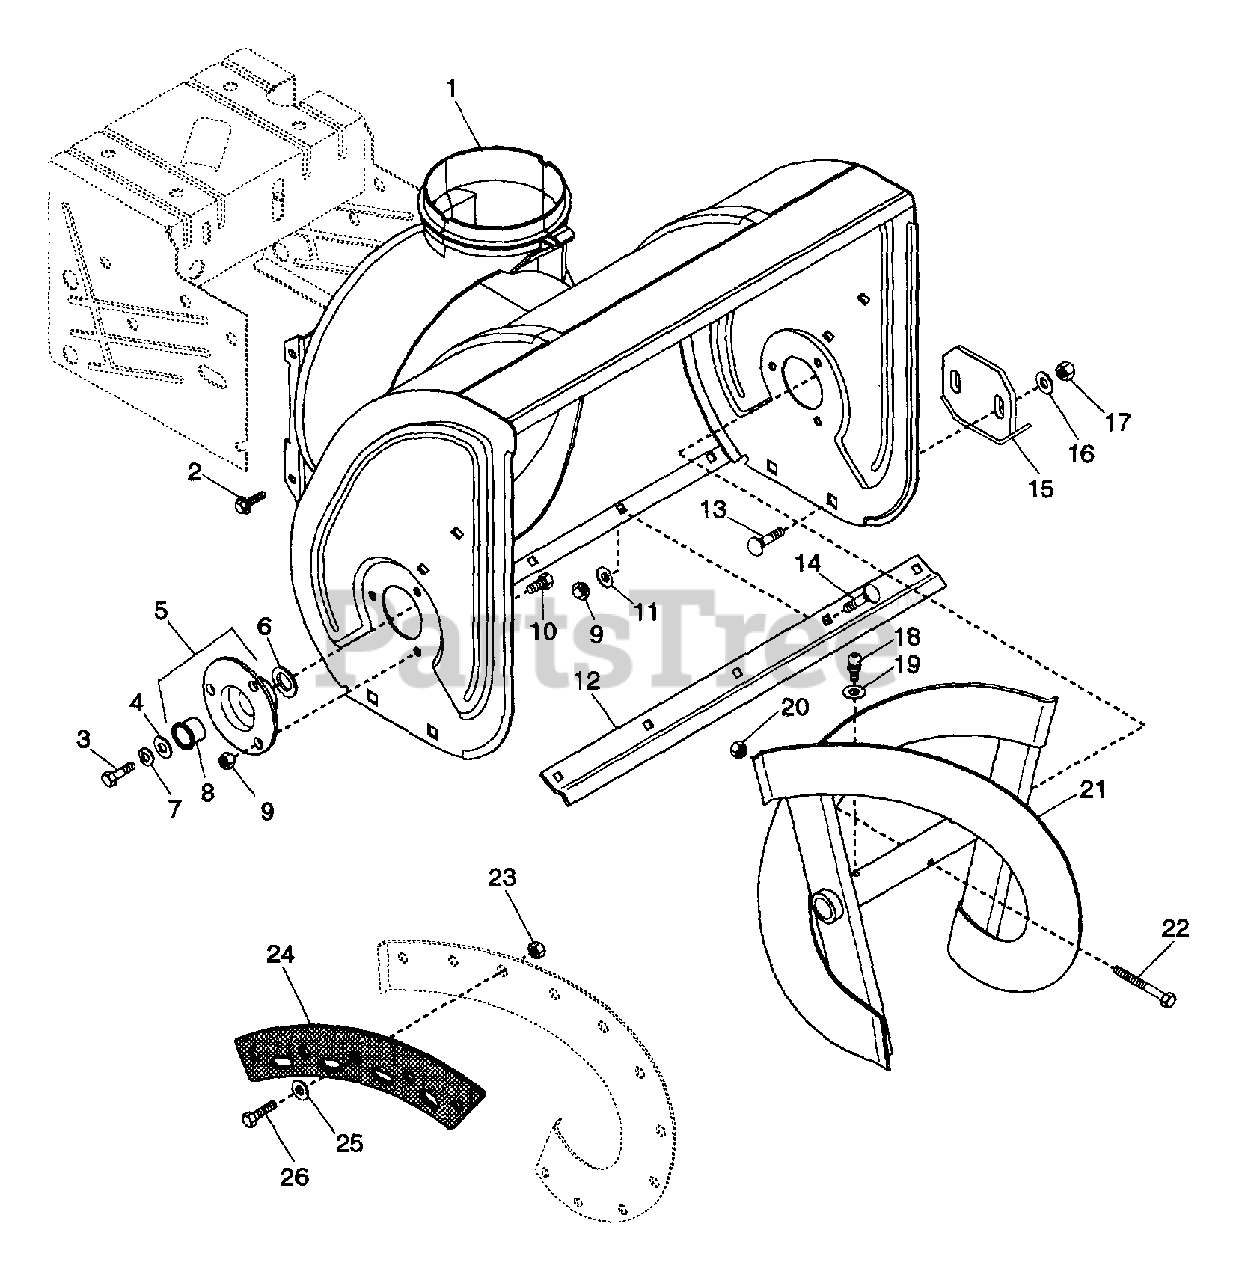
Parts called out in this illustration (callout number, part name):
1	AUGER/IMPELLER HOUSING 20" ST2
1	AUGER/IMPELLER HOUSING 24"
2	BLT-SERHFWH .31-18X.50 PL
3	BLT-HEX .31-18X.63 PL GR 2
4	WSHR-FL-STL .344X1.375X.075 PL
5	BEARING FLANGE ASSEMBLY
6	WSHR-FL-STL.812X1.500X.139
7	WSHR-LK .312X.097 PL HVY
8	BSHG-FLG .750X1.000X.625X1.250
9	NUT-LK-FLG .250-20 PL
10	BLT-SERNK SL .25-20X.50 PL
11	WSHR-FL-STL .328X1.0X.094 PL
12	SCRAPER BLADE
12	SCRAPPER SUPPORT
13	BLT-RDHDSQNK .38-16X.75 SHT PL
14	BLT-RDHDSQNK .25-20X.75 GR5PL
14	BLT-RDHDSQNK .25-20X.50 SHT PL
15	RUNNER
16	WSHR-FL-STL .38X.875X.083 PL
17	NUT-LK-CTR .375-16 GR A PL
18	FTG-LUBE .25-28X.256 YWZC
18	RAKE EDGE W/FLIGHTING
19	WSHR-FL-STL .265X.500X.087 PL
20	NUT-LK-CTR .250-20 PL
21	RAKE, RIGHT-24"(.75ID X 10.88)
21	RAKE, LEFT-24(.75ID X 10.88OD)
21	RAKE, RIGHT-20(.75ID X 10.5OD)
21	RAKE, LEFT-20"(.75ID X 10.5OD)
22	SHEAR BOLT WITH NUT
23	NUT-LK TOP 10-24 PL
24	RAKE EDGE W/HARDWARE
25	WSHR-FL-STL .194X.492X.047 PL
26	SCR-MCH 10-24X.63 HEX PL
